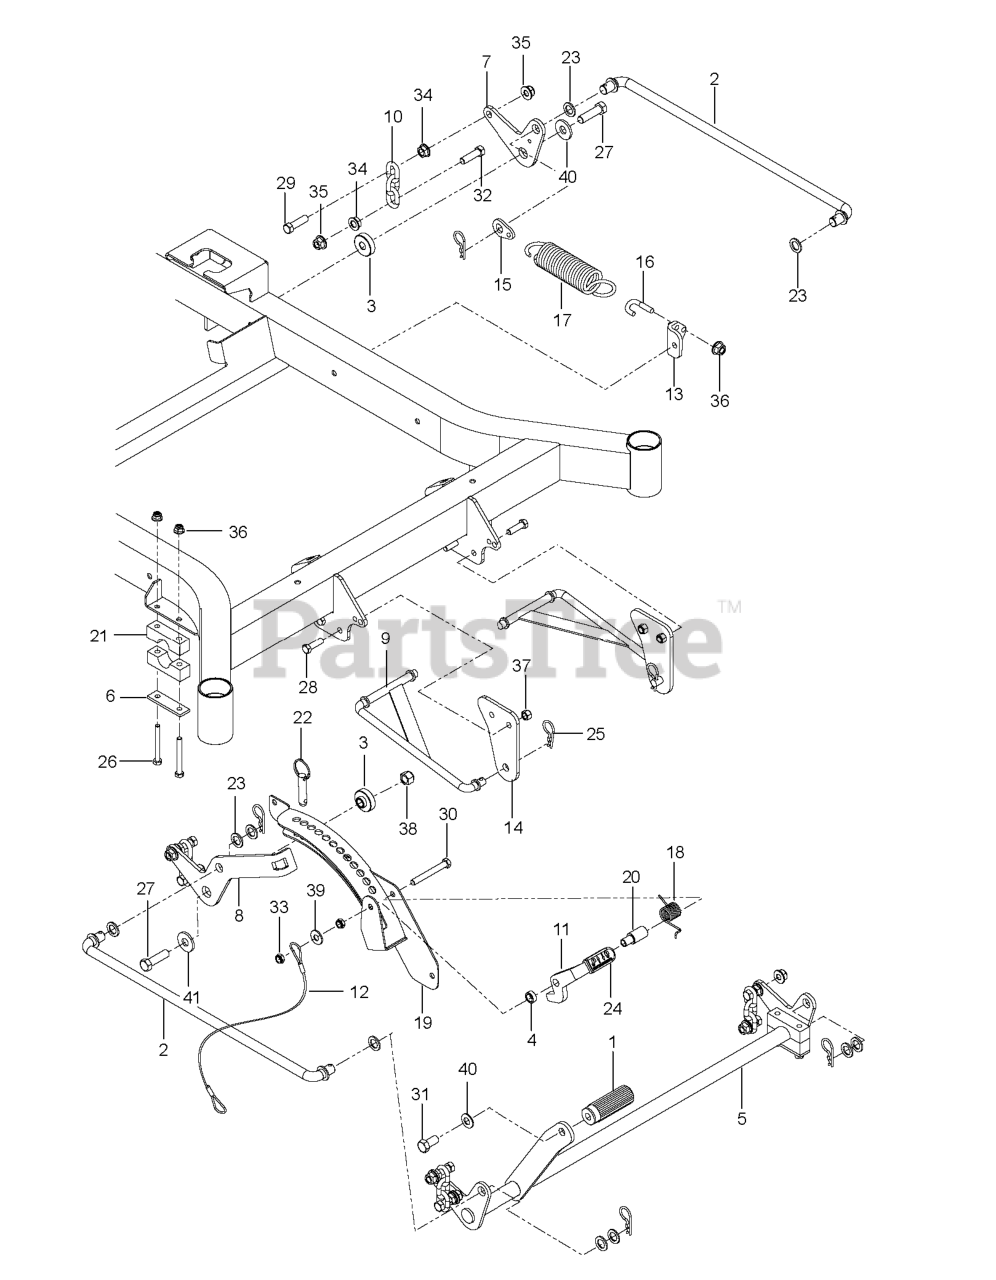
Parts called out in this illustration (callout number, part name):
1	PEDAL, DECK HEIGHT
2	CROSS LINK
3	IDLER SPACER
4	SPACER, .3
5	SHAFT FRONT LIFT BLK
6	REINFORCEMENT BAR
7	BELLCRANK, RR, LIFT
8	BELLCRANK, RR, RT
9	STRUT LINKAGE
10	LIFT CHAIN - 3 LINK
11	LATCH, TRANSPORT
13	MOUNT, SPRING
14	MOUNT, STRUT
15	TAB, SPRING
16	J-BOLT
18	SPRING, TORSION
19	HEIGHT, ADJUST, DECK
20	PIVOT, LATCH, TRANSPORT
21	PILLOW BLOCK
22	PIN, 1/2 X 1 1/2, DETENT RING
23	BUSHING
24	GRIP, TRANSPORT-RELEASE
25	PIN, COTTER 1 3/4
26	HCS 5/16C X 2-3/4
27	HCS 1/2-13 X 1 3/4 GR 8
28	HCS 3/8C X 1 1/4 GR5
29	HCS 7/16C X 1 1/2
30	HCS 3/8C X 3
31	HHCS 1/2-13 X 1
32	HCS 7/16 - 14 X 1 3/4
33	NUT 7/16-14 HEX WHIZ LK
34	NUT HEX 3/8-16 NYLON, THIN
35	NUT 1/2-13 HEX NYLOC ZD
36	5/16-18 NYLOC FLANGE NUT
37	NUT 3/8-16 NYLOC
38	NUT 7/16C WHIZ
39	RP WASHER 3/8 FLAT
40	WASHER, 7/16 DISC SPRING
41	WASH USS FLAT 1/2
